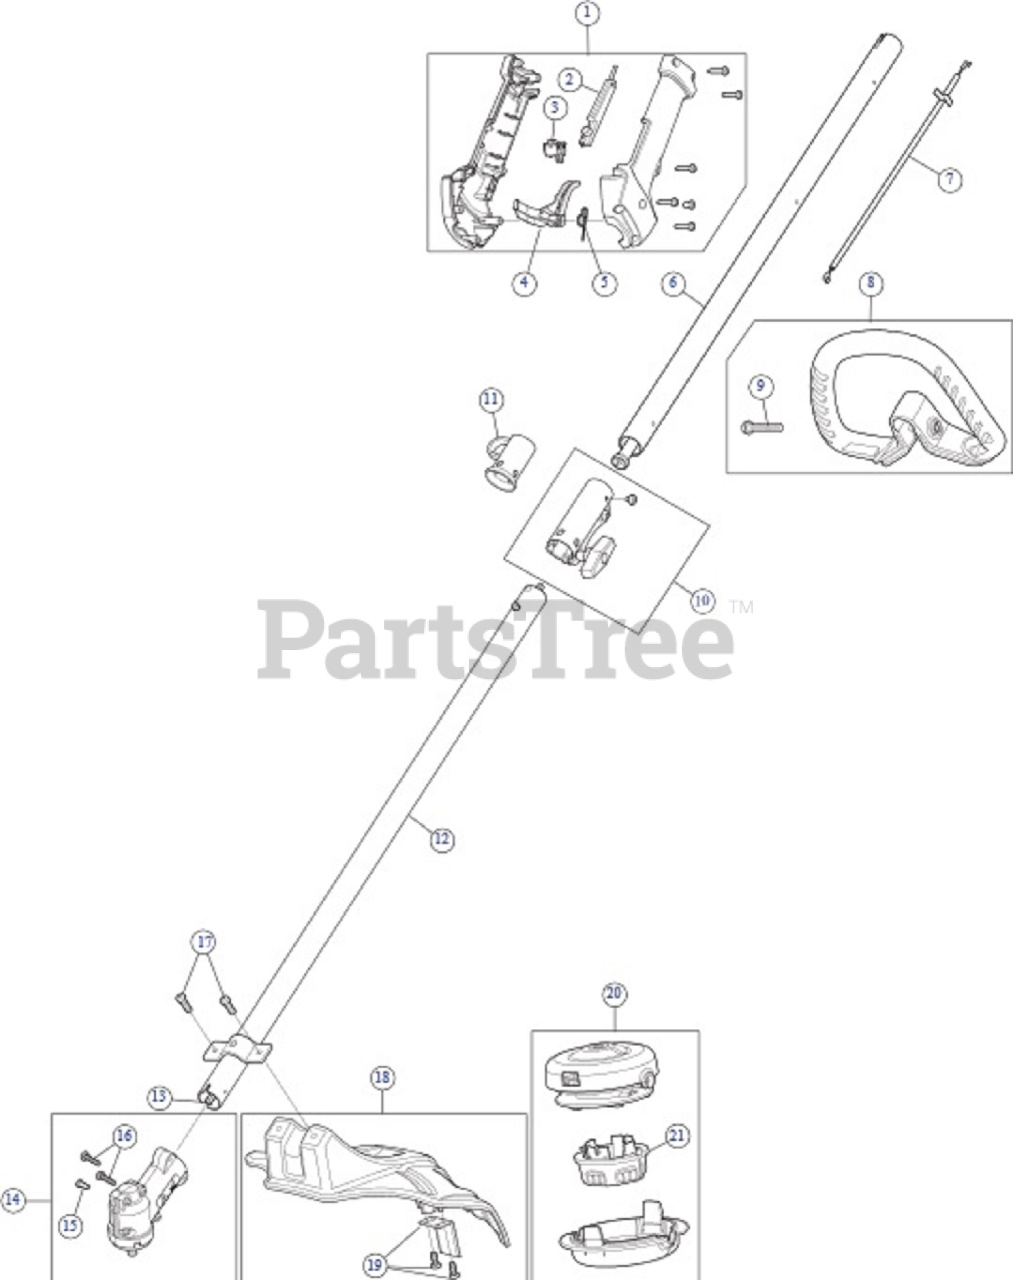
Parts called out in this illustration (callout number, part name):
1	Throttle Housing Assembly (Incl. 2 - 5)
2	Throttle Trigger Lock-Out
3	Throttle Switch Assembly
4	Throttle Trigger
5	Throttle Trigger Spring
6	Upper Drive Shaft Assembly
7	Throttle Cable
8	D-Handle Assembly (Incl. 9)
10	Split Boom Coupler
12	Lower Drive Shaft Housing
13	Lower Flexible Drive Shaft
14	Gearbox Assembly (Incl. 15 and 16)
15	Anti-Rotation Screw
16	Gearbox Mounting Hardware
17	Shield Mounting Screws
18	Shield Assembly (Incl. 19)
19	Blade Assembly
20	Cutting Head Assembly (Incl. 21)
